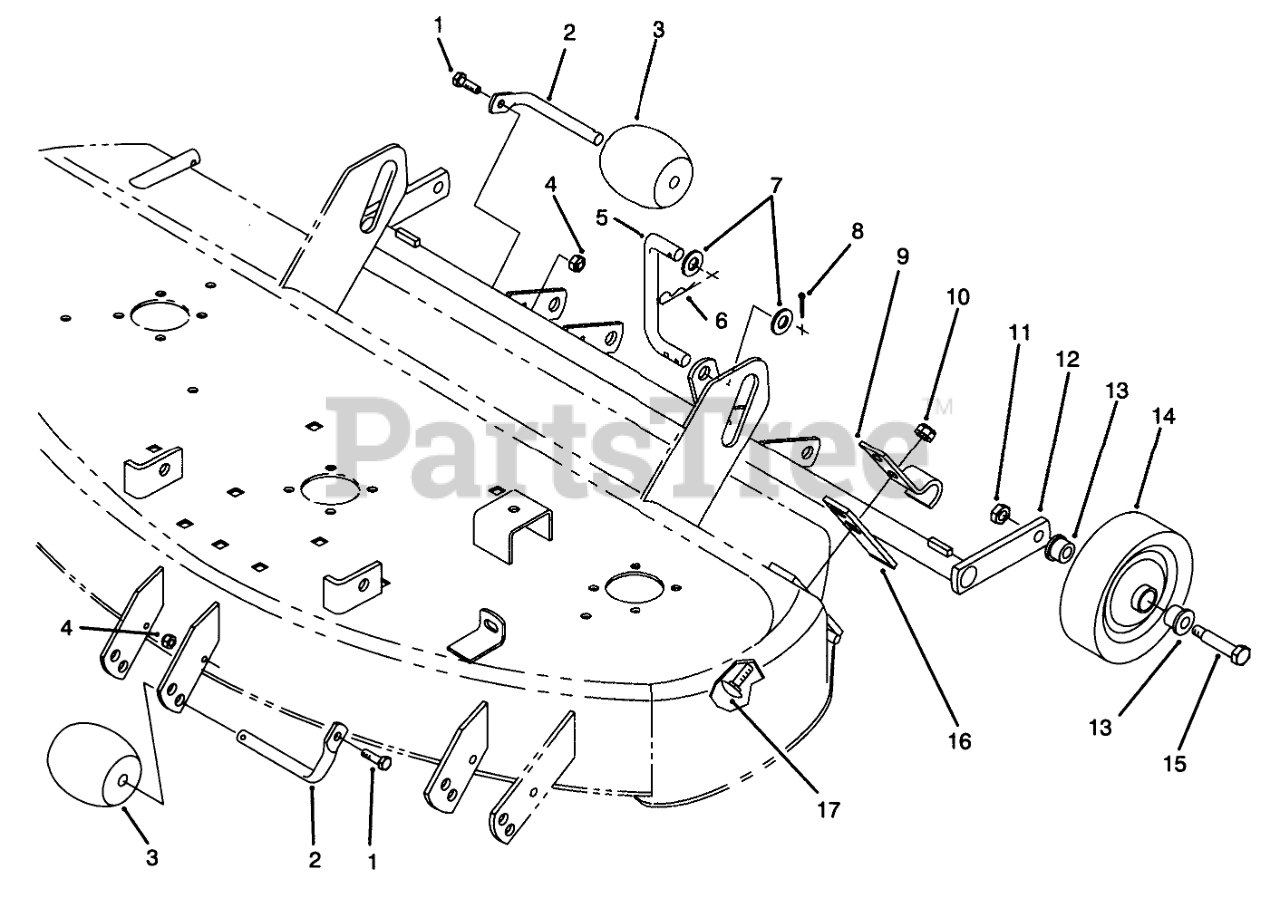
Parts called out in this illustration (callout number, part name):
1	Bolt
2	SHAFT-ROLLER
3	ROLLER
4	NUT-LOCK, NI
5	LINK-REAR
6	Pin-Cotter
7	WASHER-FLAT
8	PIN-COTTER
9	Clamp
10	NUT-LOCK, NI
11	NUT-HEX
12	Gage Wheel Support W.A.
13	BEARING
14	Assembly-Wheel(Incl. Ref. #13)
15	BOLT-SHOULDER
16	Bar
17	SCREW-CARR
